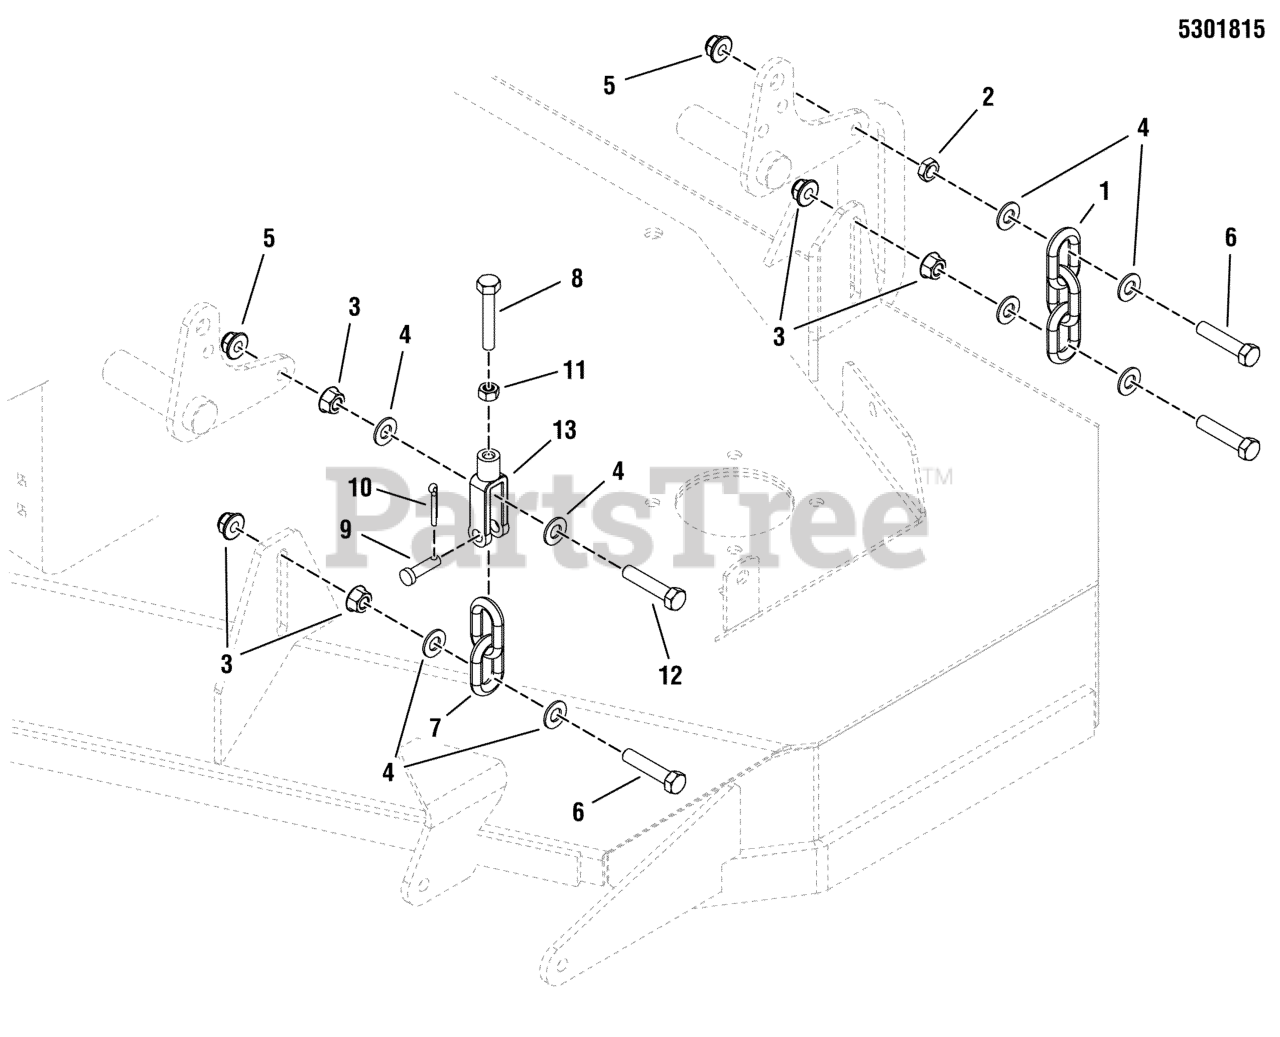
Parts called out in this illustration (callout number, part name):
1	CHAIN, 5/16 GD30, 3 LINKS
2	NUT, 3/8-16 HEX JAM
3	NUT, 3/8-16 HEX SERRATED FLANGE
4	WASHER, 3/8 SAE
5	NUT, 3/8-16 HEX NYLOCK FLANGE
6	BOLT, 3/8-16 X 1-3/4" GD5 CZ
7	CHAIN, 5/16 GD30, 2 LINKS
8	BOLT, 5/16-18 X 2 GD5 TFL
9	PIN, CLEVIS, 3/8 X 1-1/8
10	PIN, COTTER, 1/8 X 3/4
11	NUT, 5/16-18 HEX
12	BOLT, 3/8-16 X 2, GD5, CZ
13	CLEVIS, 5/16-18, 3/8 PIN HOLE
